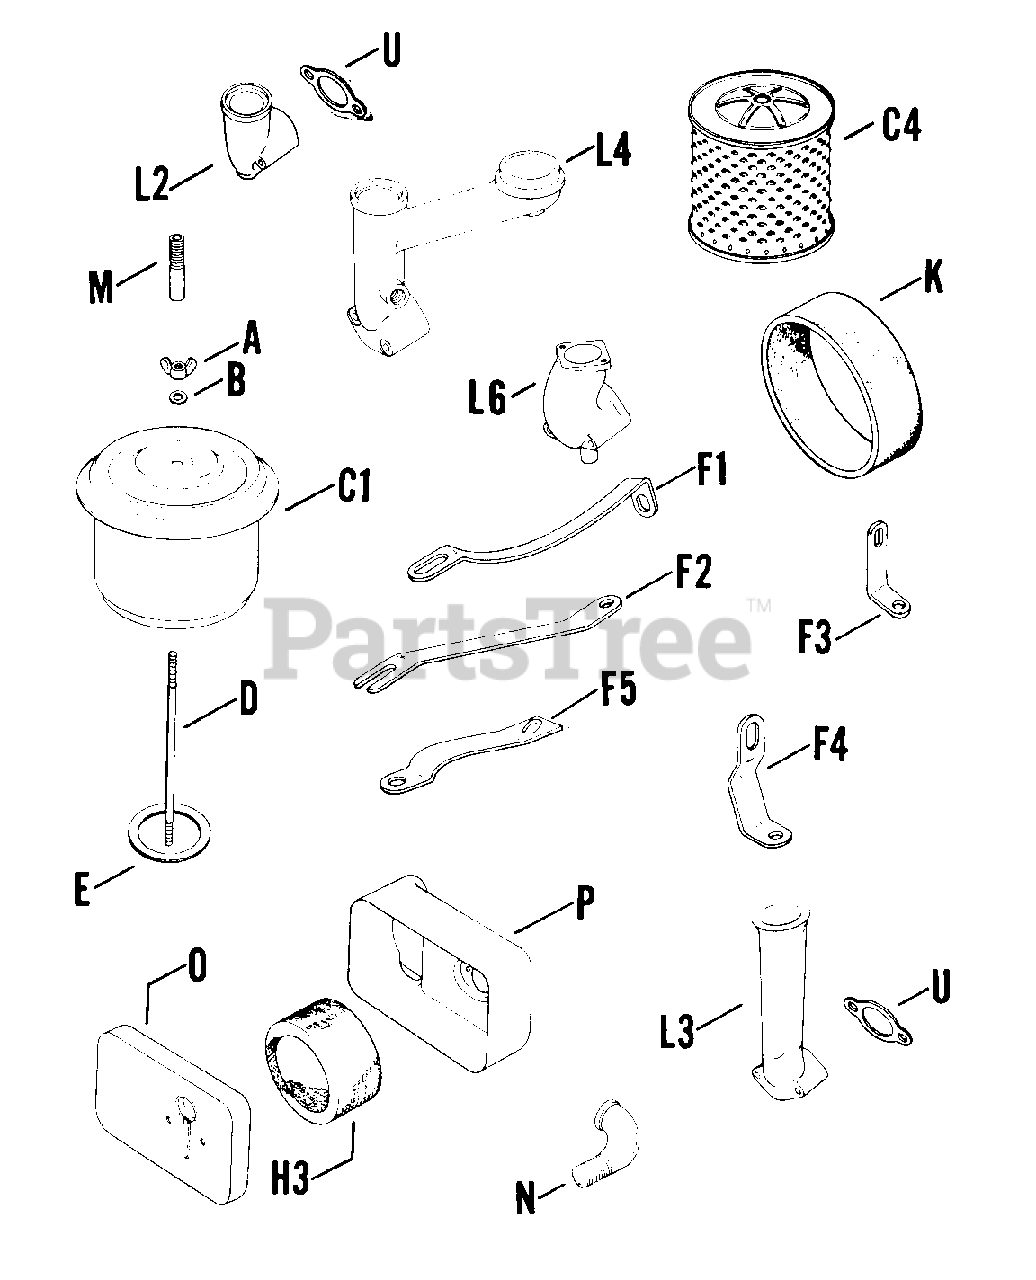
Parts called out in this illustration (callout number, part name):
A	NUT, WING 1/4-20 USE 25 100 15-S
B	WASHER - USE X-276-7
E	GASKET - DISCONTINUED
U	GASKET - USE 41 041 11
